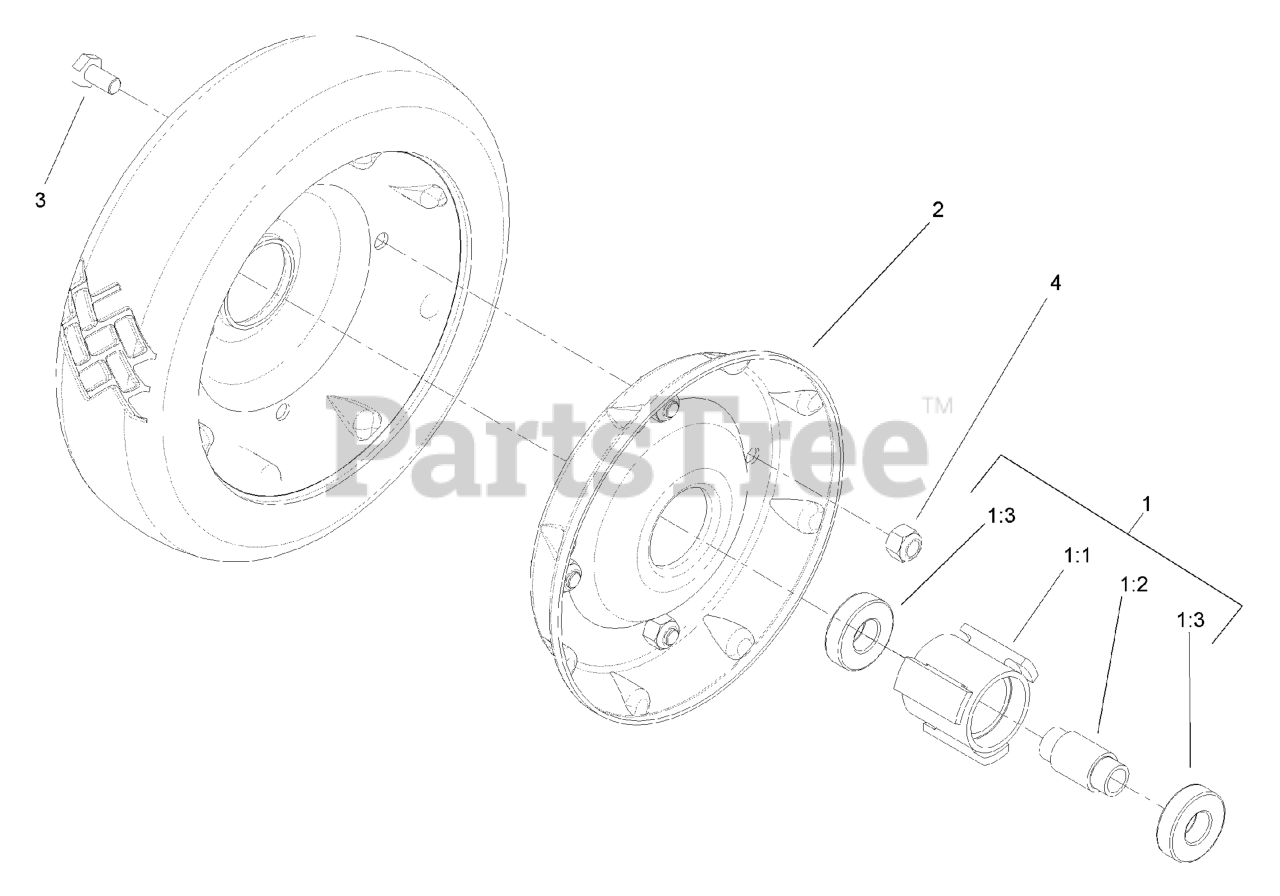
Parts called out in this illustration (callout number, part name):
1	Hub And Bearing Asm
1:1	HUB-BEARING
1:2	SPACER-BEARING
1:3	BEARING-WHEEL
3	SCREW-HH
4	NUT-LOCK, NI
